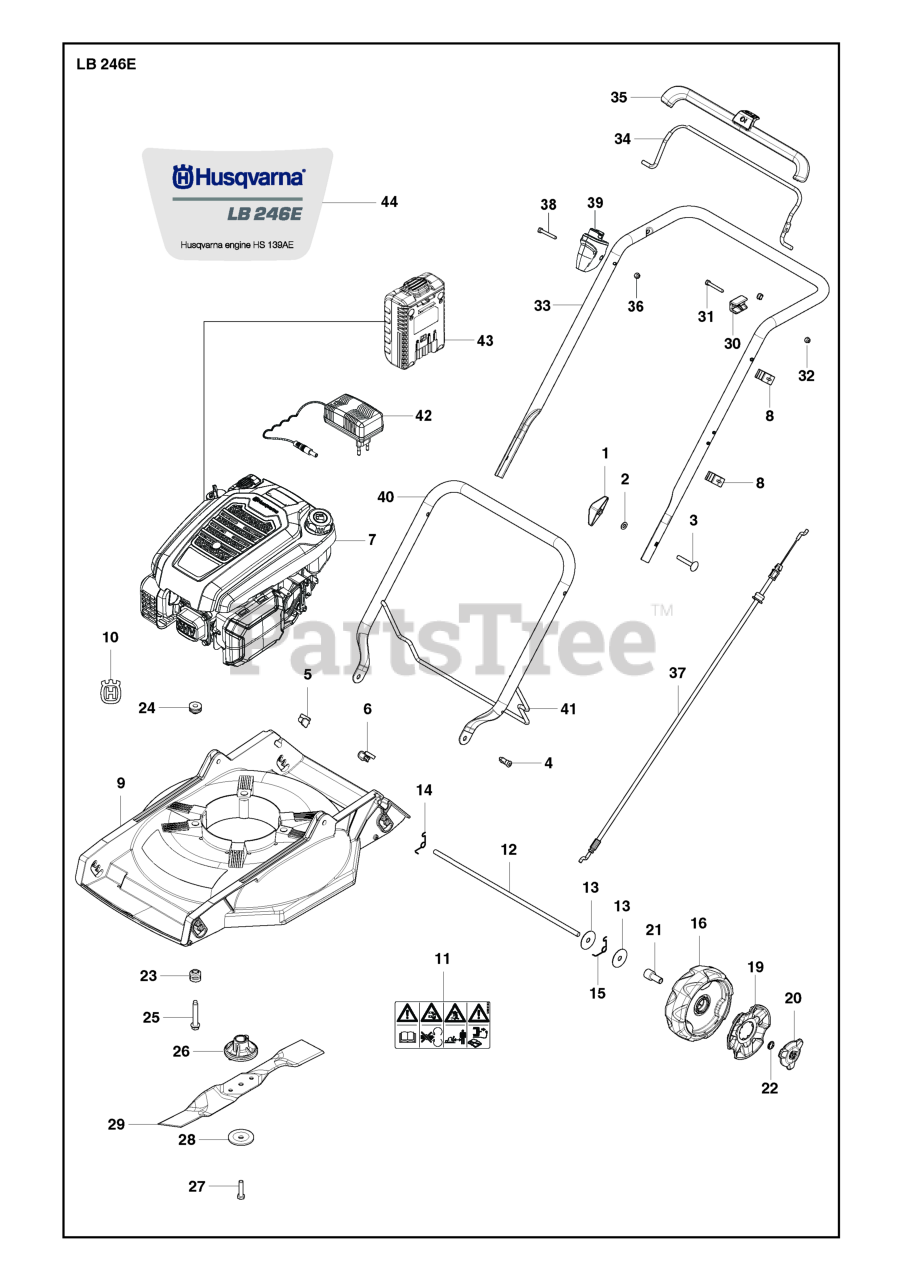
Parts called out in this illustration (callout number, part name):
1	WINGNUT
10	DECAL HUSQVARNA CROWN 41MM FLA
32	NUT FLANGE - M6
36	LOCKNUT M6
38	Hex Head Capscrew, M6 X 1.00 X 40MM
